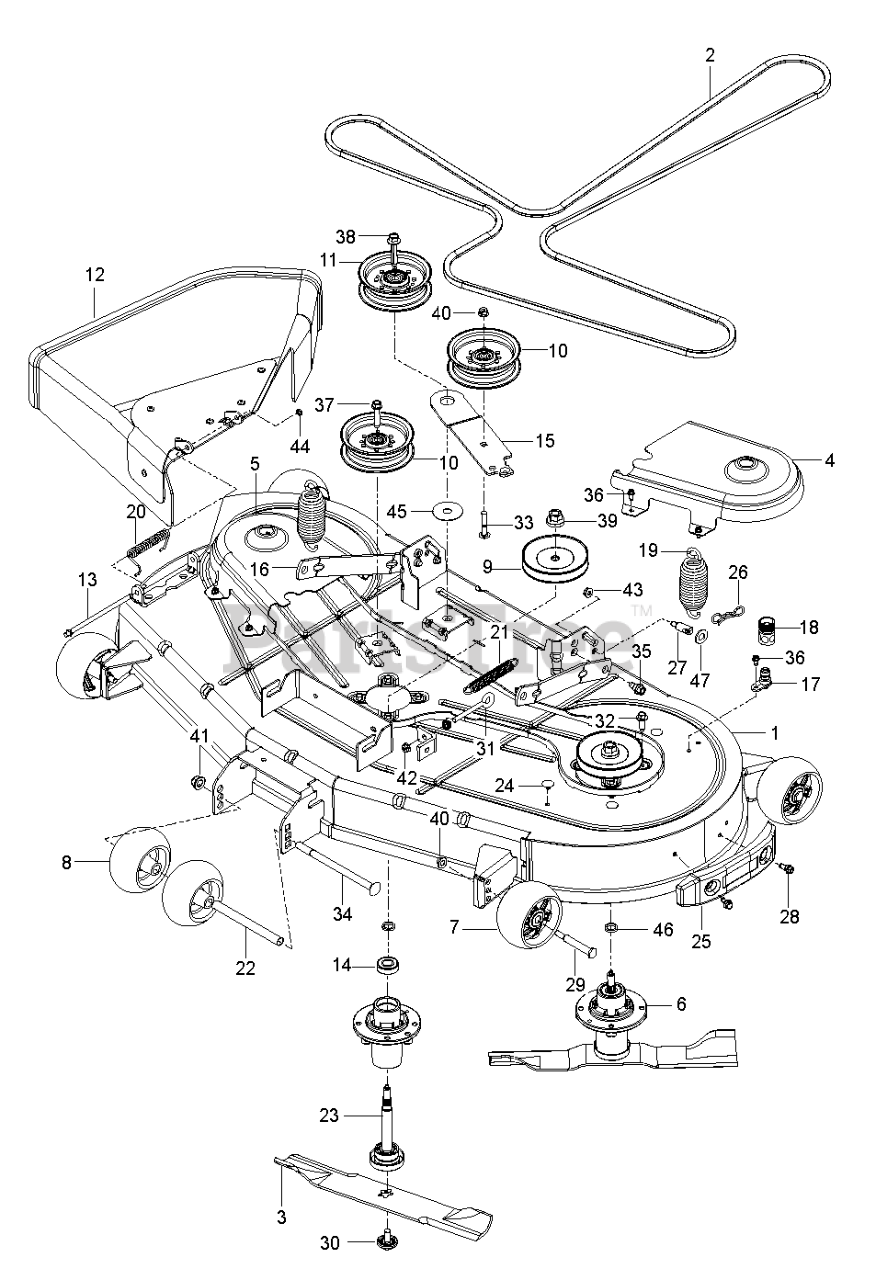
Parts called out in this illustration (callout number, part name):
1	DECK.SVC.54.CLRCT.RZ.MS668
2	BELT.54CC.DRIVE.DECK.RZ.LONG
3	BLADE CC54 PZ STYLE HI LIFT BL
4	COVER.PNT.54CC.MNDRL.LH.ZTR.GY
5	COVER 54 CLEARCUT RH MANDREL G
6	MANDREL ASM, CAST IRON
7	WHEEL.GAUGE.RALLY
8	ROLLER, GAUGE .635 BORN
9	PULLEY.MANDREL.CRD 107CM.DOM.
10	PULLEY.IDLER.2006
11	RB PULLEY.IDLER.4.50/HUB SPEC
12	DEFLECTOR ASSY 54 CLEARCUT RES
13	ROD.HINGE
15	ARM IDLER ARM, CLEARCUT 54 BLA
16	ARM.RFIXED.MOWER.SUSPNSIONX431
17	PORT.WASHOUT
18	COUPLING.QUICK CONNECT
19	SPRING
20	SPRING.42.FCS.DEFLECTOR
21	SPRING.EXTN.42.FCS.TR.DECK.DRV
22	TUBE, ROLLER AXLE LONG
23	SHAFT ASM MANDREL
24	PLUG CHRISTMAS TREE
25	BUMPER ASSY 54 CLEARCUT TRIM S
26	PIN.COTTER.7/16.BOW TI.
27	STUD.FASTNER.W/ANTI-ROTATE
28	SHOULDER BOLT 5/16-18TT
29	BOLT.SHOULDER.3/8-16X3-5/8.
30	BOLT.WASHER.ASM.7/16-2
31	EYE BOLT 5/16 X 3.50
32	BOLT.HEX.WASHR.HED.313-18X1.19
33	BOLT
34	RHSNB 1/2-13 X 8 GR5 ZD
35	BOLT.SHOULDER
36	SCREW.1/4-20X5/8
37	SCREW LT
38	SCREW.7/16-14 X 2.125.WASHER
39	NUT.FLANGE.LOCK.TOP
40	NUT LOCK FLG 3/8-16 UNC
41	NUT, 1/2-13 HEX FLG NYLOC ZD
42	NUT 5/16C WHIZ
43	NUT LOCK HEX FLANGE 5/16-18
44	NUT PUSH M
46	WASHER.SPACER.MANDREL
47	WASHER.CLEAR.ZINC
